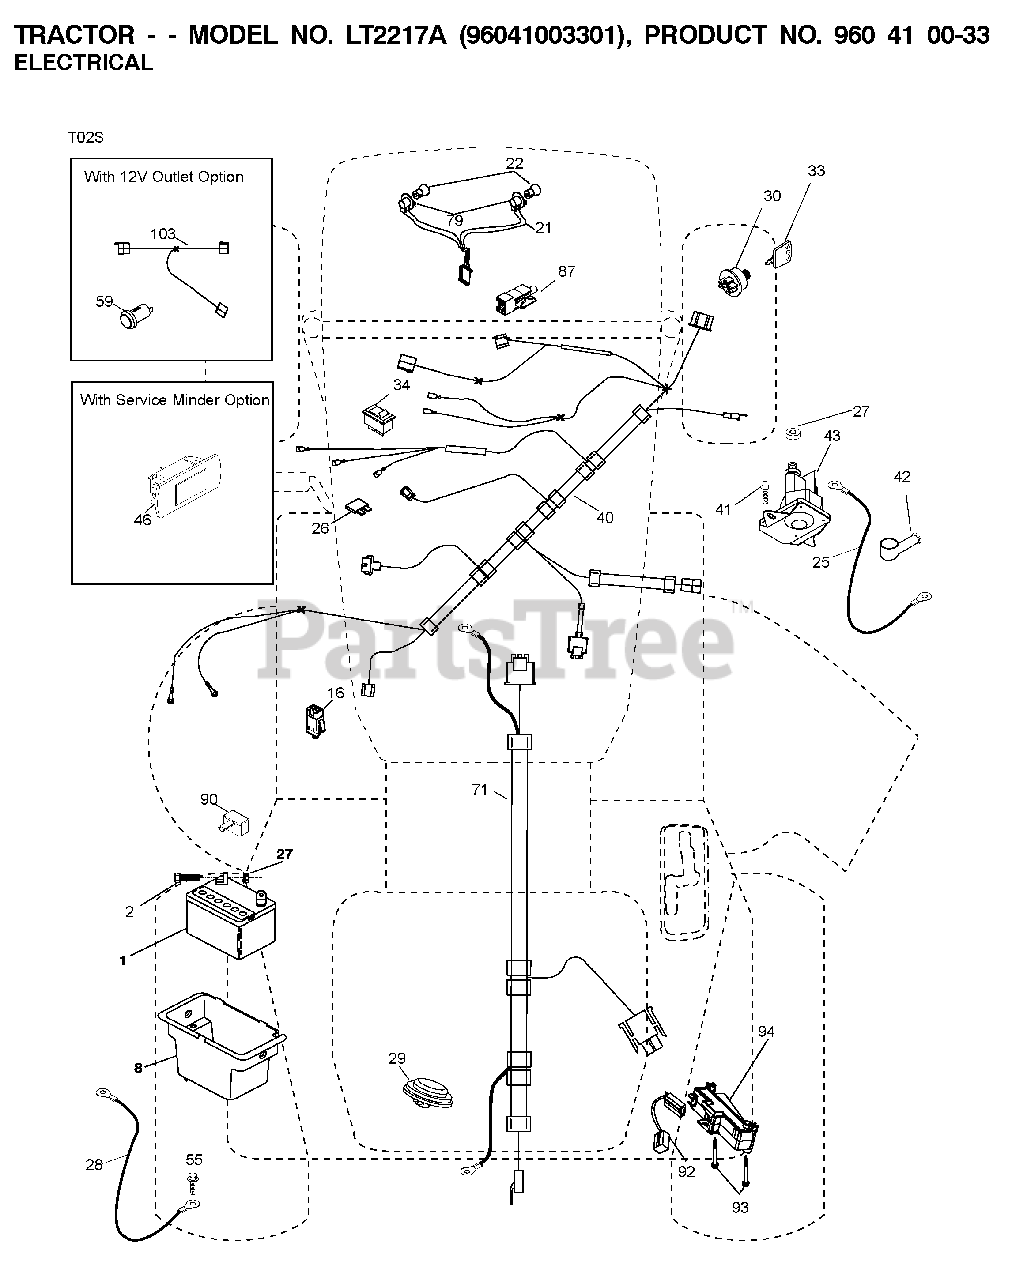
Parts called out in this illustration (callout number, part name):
1	REPL BY 532 12 38-99
8	BOX.BATTERY.MNT.REAR.L
16	SWITCH INTERLOOK PUSH-IN
21	HARNESS ASSY LIGHT
22	LIGHTBULB
25	CABLE.STARTER.6GA.RED.
26	FUSE 20AMP
27	NUT
28	CABLE.BLACK.18"REAR.BA
29	SWITCH.SEAT.DELTA.OPC.
30	SWITCH.IGN.DELTA.W.LGH.ROS
33	KEY.CHAIN.BLISTER.PACK.GEN.INT
34	SWITCH LT
40	HARNESS.IGN.CHASS.TEX.REAR.BAT
41	SCREW
42	TERMINAL COVER
43	SOLENOID.W/BRASS.PLUNG
55	SCREW 5/16"
71	HARNESS IGN. DASH
79	BULB HOLDER ASM.
87	SWITCH.INTRLCK.CLUTCH.
90	COVER, TERMINAL BATTERY
92	HARNESS.PIGTAIL.CONSLE
93	SCREW.PLASTITE
94	MODULE.REVERSE.ROS
